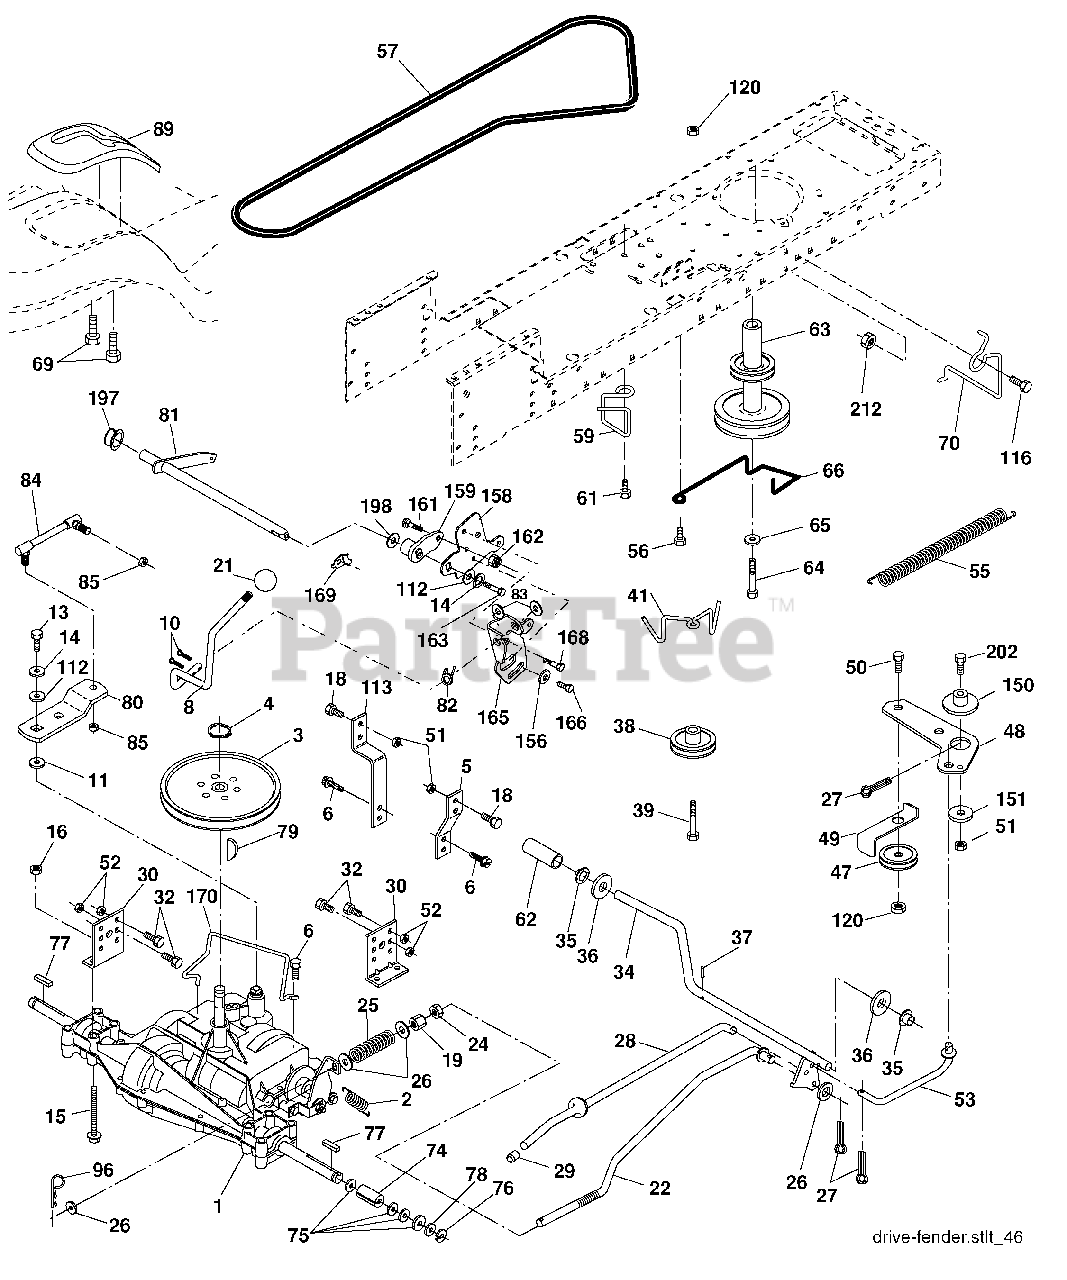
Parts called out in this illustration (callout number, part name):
1	Transaxle Dana D4360-139 (See Breakdown)
2	Spring Brake Return
3	Pulley Transaxle
4	Ring Retainer
5	Strap Torque 30 Degrees
6	Screw 5/16-18 x 3/4
8	Rod Shift Fender Adjust
10	Pin Cotter 1/8 x 1 CAD
11	Washer Plate Shift
13	Bolt 1/4-28 unf Gr. 8 W/Patch
14	Washer Lock Hvy Helical
15	Bolt Hex FLGHD 5/16-18 x Gr. 5
16	Nut Lock Hex W/Ins. 5/16-18 unc
18	Bolt Fin Hex 3/8-16 x 1 Gr. 5
19	Nut Lock Hex W/Wsh 3/8-16 unc
21	Knob
22	Rod, Brake
24	Nut, Hex Jam 3/8-16 unc
25	Spring, Brake Rod
26	Washer 13/32 x 13/16 Ga.
27	Pin Cotter 1/8 x 3/4 CAD.
28	Rod, Parking Brake
29	Cap, Parking Brake
30	Bracket, Transaxle
32	Bolt Hex Hd 5/16-18 unc x 3/4
34	Shaft, Foot Pedal
35	Bearing, Nylon
36	Washer
37	Pin, Roll
38	Pulley, Composite, Flat
39	Bolt Fin Hex 3/8-16 x 2-3/4
41	Keeper, Belt Idler
47	Pulley, Idler, V-Groove
48	Bellcrank, Clutch
49	Retainer, Belt
50	Bolt Carr 3/8-16 x 1-1/2
51	Nut Crownlock 3/8-16 unc
52	Nut, Crownlock 5/16-18 unc
53	Link, Clutch
55	Spring, Return, Clutch
56	Screw 3/8-16 x 1-1/4
57	V-Belt
59	Keeper, Center Span
61	Screw, 3/8-16 x .875
62	Cover, Pedal
63	Pulley, Engine
64	Bolt Hex 7/16-20 x 4 Gr. 5-1.5
65	Washer Lock 7/16
66	Keeper Belt Engine Hydro
69	Screw Hex Wsh Hi-Lo 1/4 x 1/2 unc
70	Keeper Belt Engine
74	Spacer
75	Washer 25/32 x 1-1/4 x 16 Ga.
76	E-Ring
77	Key, Square
78	Washer 25/32 x 1-5/8 x 16 Ga.
79	Key Woodruff
80	Arm Shift
81	Shaft Asm Cross Tapered
82	Spring Torsion
83	Washer 17/32 x 3/4 x 16 Ga.
84	Link Transaxle
85	Nut Lock Center 1/4-20
89	Console, Shift
96	Retainer Spring 1" Zinc/Cad
112	Washer 9/32 x 3/4 x 10 Ga.
113	Strap Torque 90 Degrees
116	Bolt Rdhd Sqneck 3/8-16 x 1.25
120	Nut Lock Flg 3/8-16
150	Spacer Retainer
151	Washer 13/32 x 2 x 10 Ga.
156	Washer Srrted 5/16 ID x 1.125
158	Bracket Shift Mount
159	Hub Shift
161	Bolt Rdhd Sqnk 1/4-20 x 3/4 Gr. 5
162	Nut Crownlock 1/4-20 unc
163	Bolt Hex Fin 1/4-20 unc x 1 Gr. 5
165	Bracket Pivot Lever
166	Screw 5/16-18 x 5/8
168	Bolt Shoulder 5/16-18 x .561
169	Plate Fastening
170	Keeper Belt T/A
197	Nyliner Snap-In 5/8’’ID
198	Washer Nyl
202	Bolt Carr Sh 3/8-16 x 1-3/4 Gr. 5
212	Nut Hex Flg. Lock
